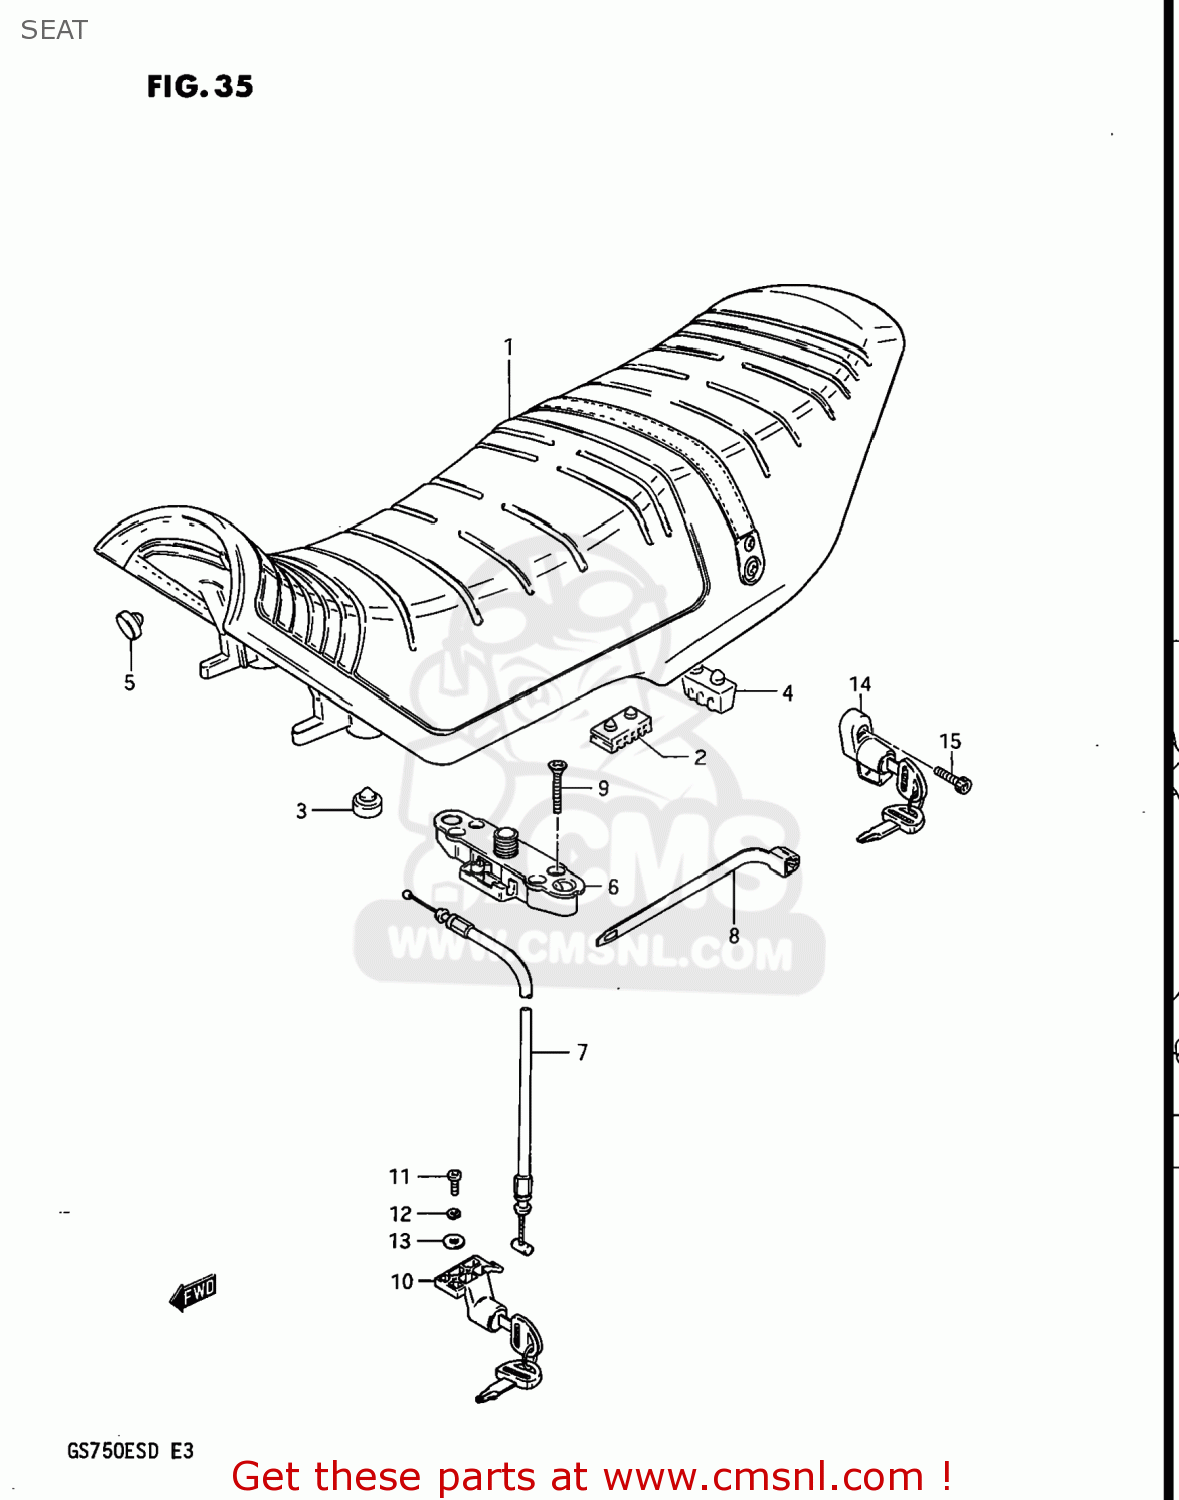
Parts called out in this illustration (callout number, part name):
1	SEAT ASSEMBLY
2	CUSHION,SEAT(40X20X15)
3	CUSHION(11.5X22X20)
4	CUSHION
5	CUSHION,SUPPORT(50X25X32)
6	WEATHERSTRIP,SEAT
7	LOCK ASSEMBLY,SEAT STRIKER
8	CABLE,SEAT LOCK
9	CLAMP(L:165)
10	SCREW
11	LOCK ASSEMBLY,SEAT
12	BOLT
13	LOCK WASHER
14	WASHER
15	LOCK SET
16	BOLT
